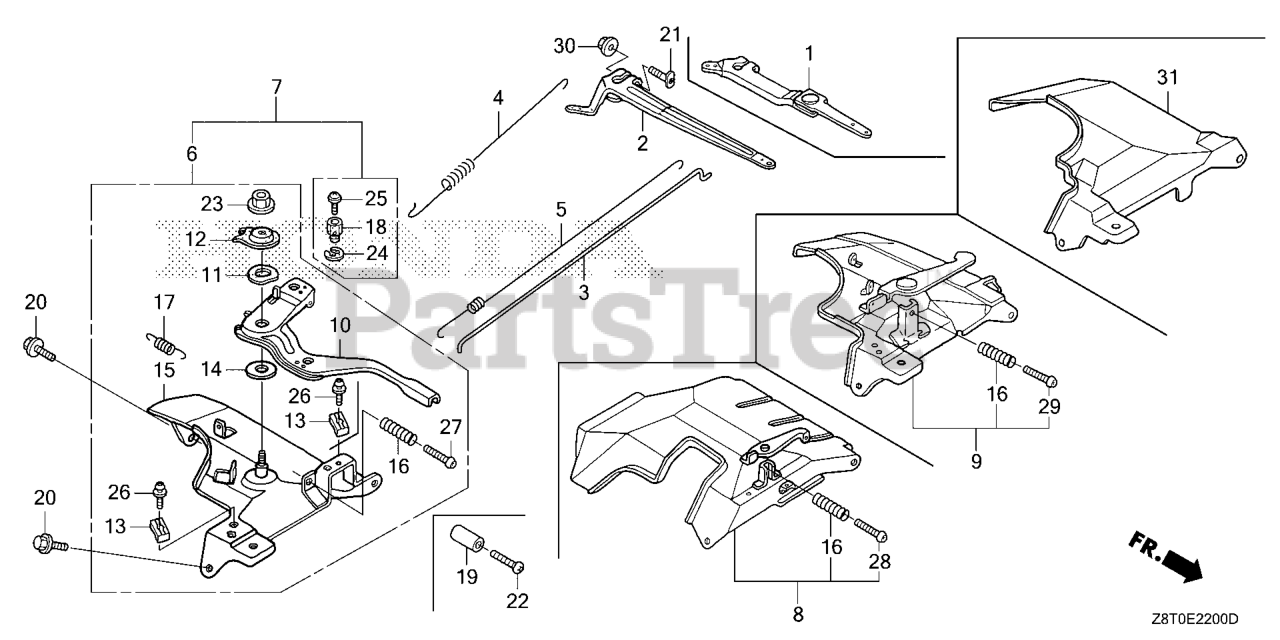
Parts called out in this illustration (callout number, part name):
2	ARM, GOVERNOR
3	ROD, GOVERNOR
4	SPRING, GOVERNOR
5	SPRING, THROTTLE RETURN
6	CONTROL ASSY. (REMOTE)(ROD)
10	LEVER, CONTROL
11	SPRING, LEVER
12	WASHER, CONTROL LEVER
13	HOLDER, CABLE
14	SPACER, CONTROL LEVER
15	BASE, CONTROL
16	SPRING, CONTROL ADJUSTING Use from Engine SN 2327377.
17	SPRING, CABLE RETURN
20	BOLT, FLANGE (6X12) (CT200)
21	BOLT, GOVERNOR ARM
23	NUT, SELF-LOCK (6MM)
26	SCREW, PAN (5X16)
27	SCREW, PAN (5X32)
30	NUT, FLANGE (6MM)
